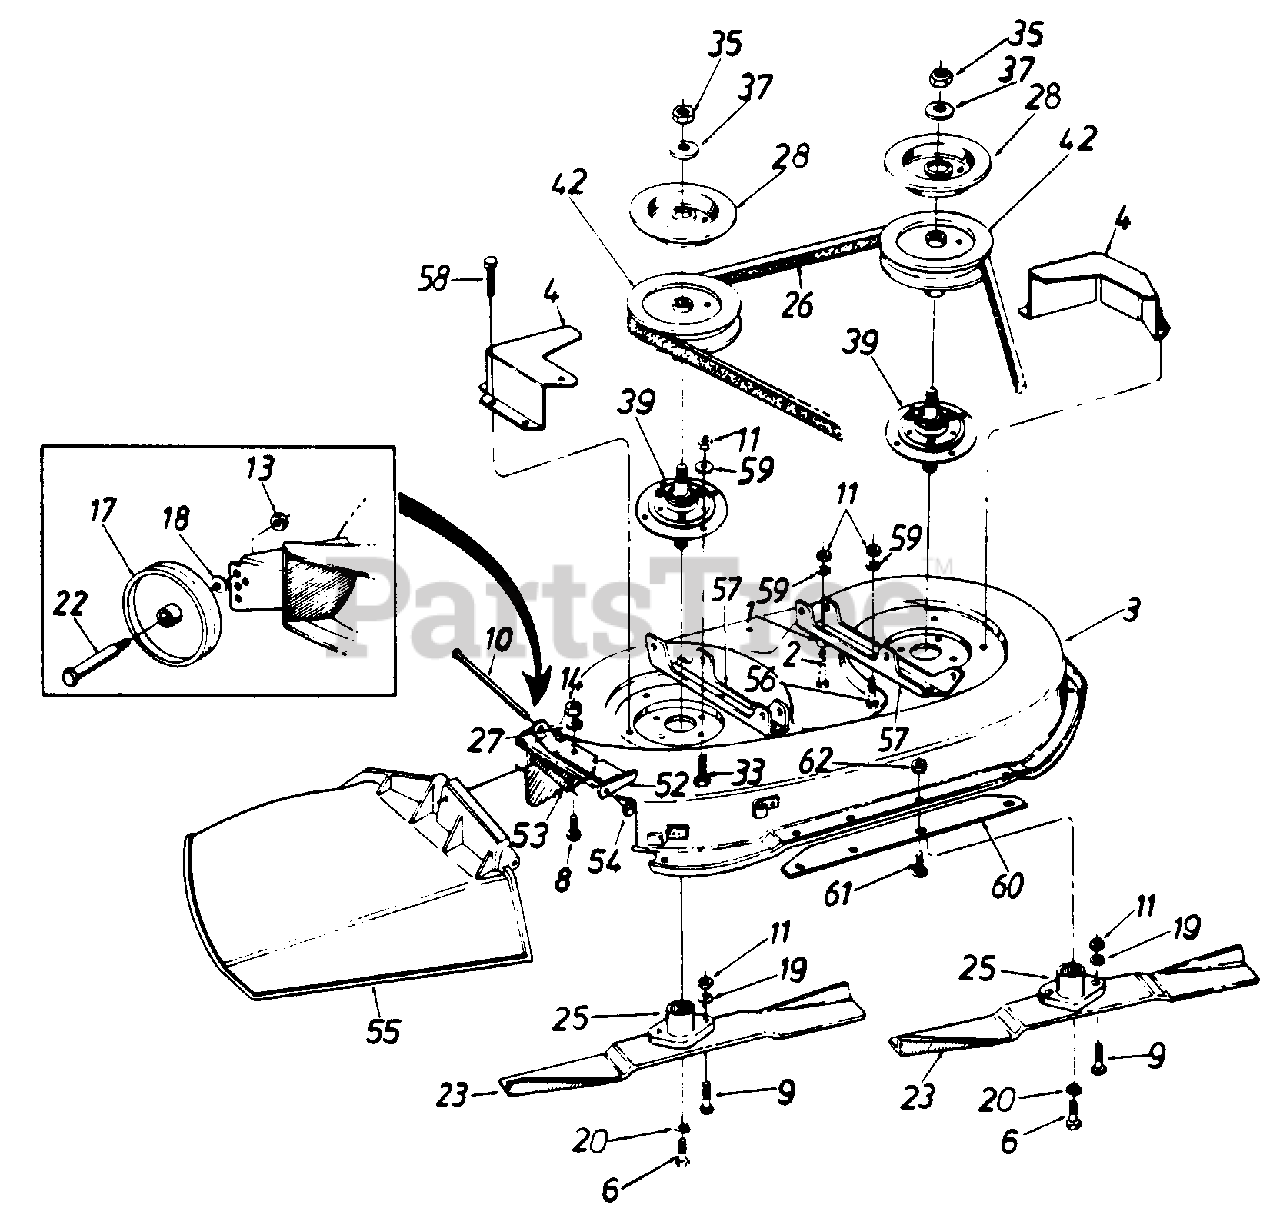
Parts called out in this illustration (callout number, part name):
1	Spacer .33" I.D. x .88"
2	Hex Bolt 5/16-24 x 1.25" Lg.
6	Hex Bolt 3/8-24 x 1.0" Lg.
8	Hex Bolt 1/4-20 x .62"
9	Hex Bolt Special 5/16-24 x 1.0"
10	Hinge Pin
11	Hex Nut 5/16-24 Thd.
13	Hex Top L-Nut 3/8-16 Thd.
14	Hex Nut 1/4-20 Thd.
17	Deck Wheel - 5"
18	Bell-Wash. .40" I.D. x .88" O.D.
19	L-Wash. 5/16" I.D.
20	L-Wash. .3/8 I.D.- H.D.
22	Shld. Bolt .498 Dia. x 1.53"
23	High-Lift Blade
25	Blade Adapter
26	V-Belt
27	Bell-Wash. 1/4" I.D.
28	Brake Disc
33	Hex Bolt 5/16-24 x .75" Lg.
35	Hex Jam Nut 5/8-18 Thd.
37	L-Wash. 5/8" I.D.
39	Blade Spindle Ass'y. Comp.
42	5" Dia. Pulley
52	Hinge Mtg. Brkt.
53	Torsion Spring
55	Chute Ass'y. Comp.
56	Hex Bolt 5/16-24 x .75" Lg.
59	Bell-Wash. 34" I.D. x .88"
62	Hex Sems Nut 1/4-20 Thd.
